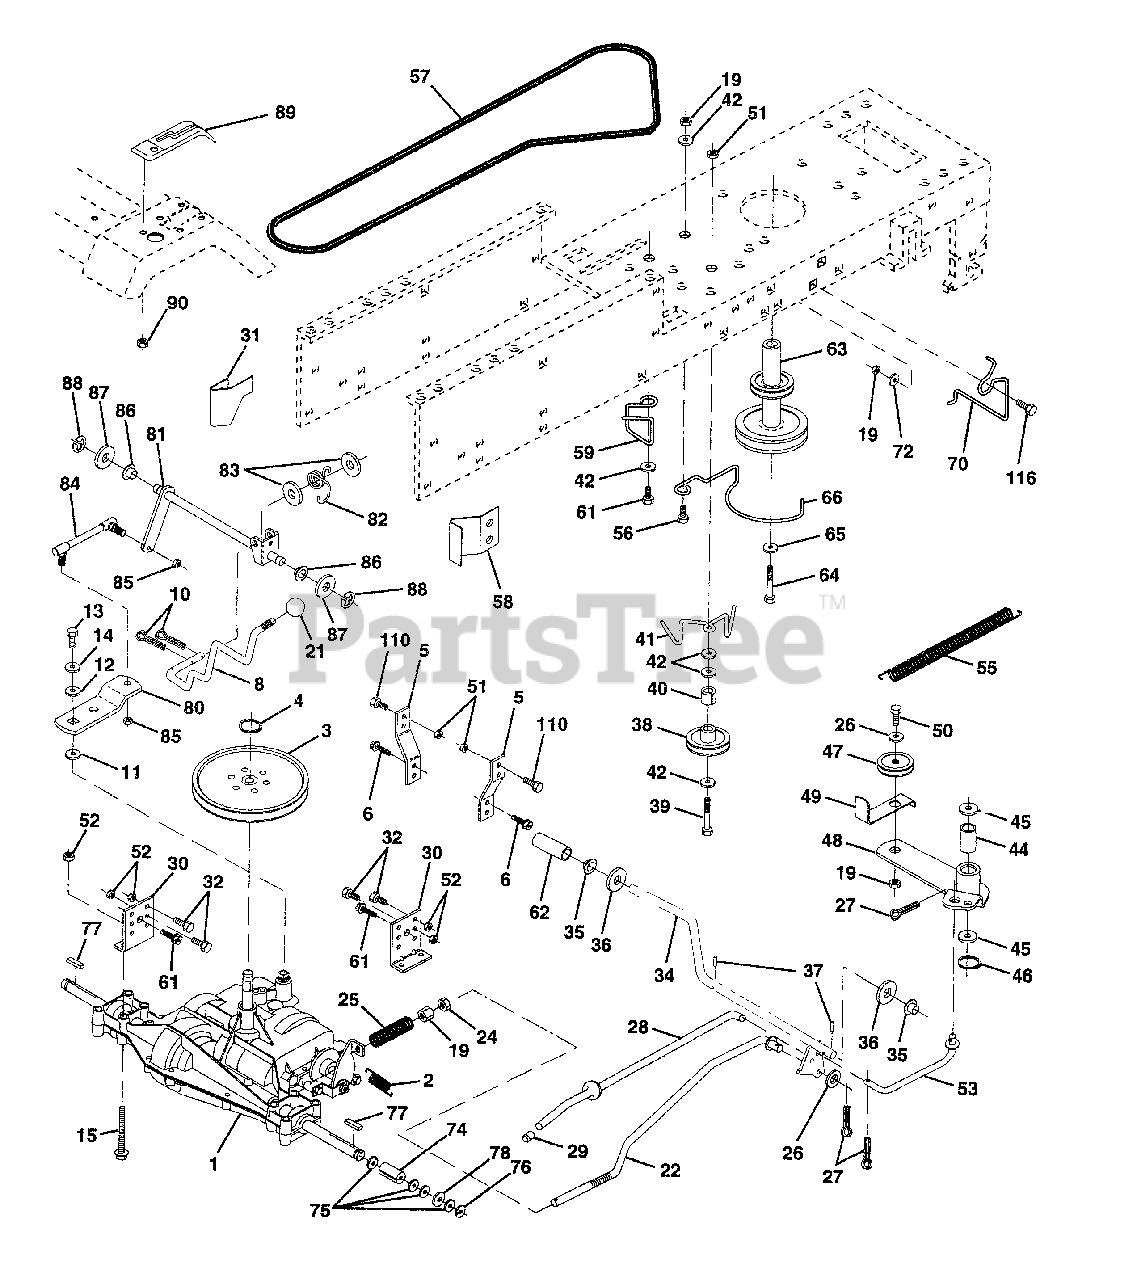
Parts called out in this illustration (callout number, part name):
1	Transaxle 6sp Dana 4360-96
2	Spring Return Brake T/a Zinc
3	Pulley Transaxle 18"tires
4	Ring Retainer # 5100-62
5	Strap Torque 30 Degrees
6	Screw Thdrol 5/16-18 X 3/4 TYT
8	Rod Shifter
10	Pin Cotter 1/8 X 1 Cad
11	Washer Plate Shf 388 Sq Hole
12	Washer 15/32 X 3/4 X 16 Ga
13	Bolt 1/4-28 Unf Gr 8 W/Patch
14	Washer Lock Hvy Helical 1/4
15	Bolt Hex 5/16-18FLGHD Gr. 5
18	Bolt Fin Hex 3/8-16unc X 1 Gr. 5
19	Nut Lock 3/8-16 Unc
21	Knob Duckhead 1/2-13 Plstc Thds Blk
22	Rod Brake Blk Zinc 26 840
24	Nut Hex Jam 3/8-16 Unc
25	Spring Rod Brake 2 00 Zinc
26	Washer 13/32 X 13/16 X 16 Ga
27	Pin Cotter 1/8 X 3/4 Cad
28	Rod Brake Parking LT/YT
29	Cap Brake Parking Black
30	Bracket Mtg Transaxle
31	Keeper Belt LH LT 14 Ga
32	Bolt Hex Hd 5/16-18unc X 3/4
34	Shaft Asm Pedal Foot
35	Bearing Nylon Blk 629 Id
36	Washer 21/32 X 1 X 16 Ga
37	Pin Roll 3/16 X 1"
38	Pulley Idler Flat
39	Bolt Fin Hex 3/8-16unc X 2-3/4
40	Spacer Split 395 X 59 Bzp
41	Keeper Belt Idler
42	Washer 13/32 X 13/16 X 12 Ga
44	Bearing Nyl 503 X 628 X 1 25
45	Washer Hardened
46	Ring Klip #t5304-50
47	Pulley Idler V Groove Plastic
48	Bellcrank Asm Clutch
49	Retainer Belt Style Spring
50	Bolt Hex Hd 3/8-16unc X 1-1 /2
51	Nut Crownlock 3/8-16 Unc
52	Nut Crownlock 5/16-18 Unc
53	Link Clutch 7 66
55	Spring Return Clutch 6 75
56	Bolt Fin Hx 3/8-16 X 1/4
57	V-Belt Ground Drive 95 25 42"
58	Keeper Belt RH LT Pnt/zinc 16g
59	Keeper Belt Span Ctr
61	Screw Thdrol 3/8-16x3/4 Ty-tt
62	Cover Pedal Blk Round
63	Engine Pulley LT/YT
64	Bolt Hex 7/16-20 x 4 Gr. 5
65	Washer Lock Hvy Hlcl Spr 7/16
66	Keeper Belt Engine LH LT
70	Guide Belt Mower Drive RH
72	Washer 13/32 X 1-1/4 X 12 Ga
74	Spacer Split
75	Washer 25/32 X 1 1/4 X 16 Ga
76	E-ring #5133-75
77	Key Square 2 0 X 1845/ 1865
78	Washer 25/32 X 1-5/8 X 16 Ga
80	Arm Shift Transaxle
81	Shaft Asm Cross 20"t 42"deck
82	Spring Torsion T/a
83	Washer 17/32 X 3/4 X 16 Ga
84	Rod Shift Adj Tie
85	Nut, Centelock 1/4 - 28
86	Bushing Rod Strg 629/632 Id
87	Washer 21/32 X 1-1/4 X 16 Ga
88	Ring Klip #5304-62
89	Console Shift 6sp LT
90	Nut Self-thd Wsh-hd 1/4 Zinc
110	Bolt Fin Hex 3/8-16 Unc x 3/4
116	Bolt Rdhd Sqneck 3/8-16 x 1.25
